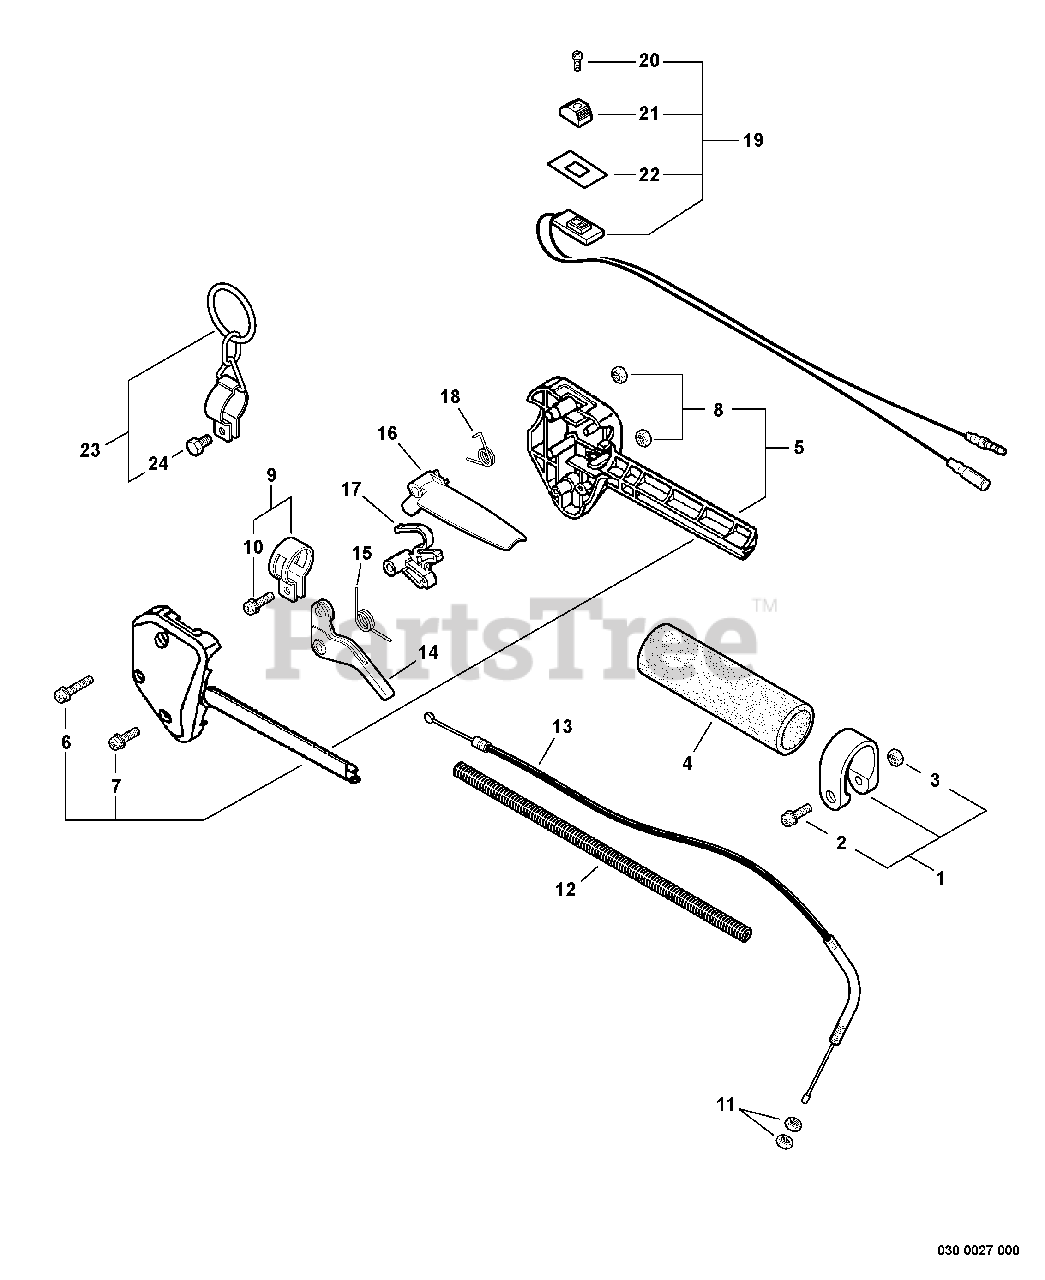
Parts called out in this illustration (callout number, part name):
1	CLAMP KIT
2	SCREW - 5X28
4	GRIP, HANDLE
5	CONTROL HANDLE KIT
6	SCREW - 5X35
7	SCREW - 5X25
9	CLAMP KIT
10	SCREW - 5X14
12	TUBE, PROTECTIVE - CORRUGATED
13	CABLE, THROTTLE
14	TRIGGER, THROTTLE
15	SPRING, TRIGGER
16	LEVER, TRIGGER LOCKOUT
17	LOCKOUT, THROTTLE
18	SPRING, LOCKOUT LEVER
19	IGNITION SWITCH ASSY
20	SCREW - 3X10
21	KNOB, SWITCH - ORANGE
22	COVER, SWITCH - STOP
23	HANGER KIT
24	BOLT - 5X12
